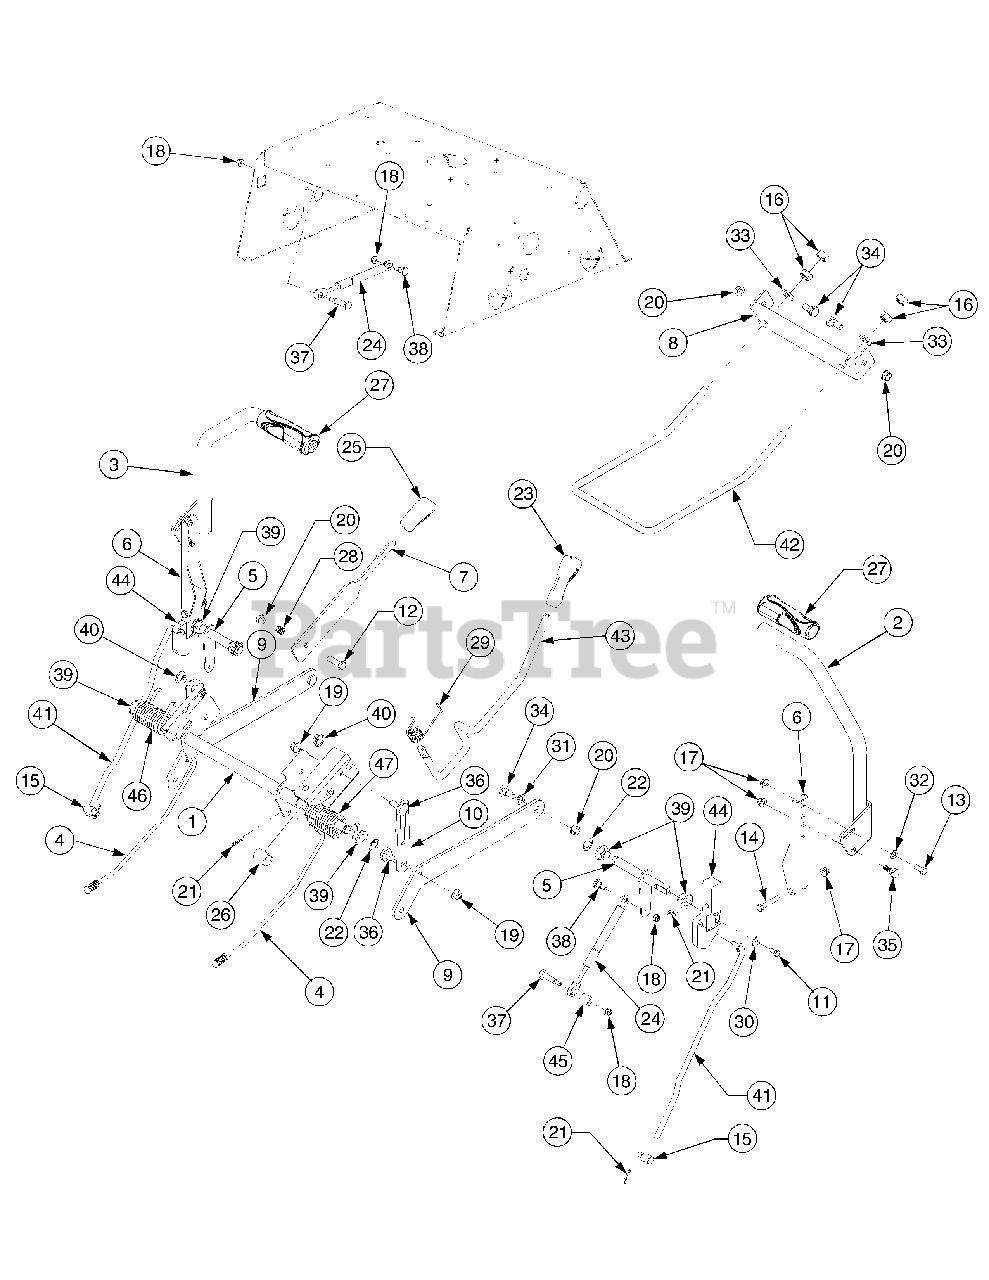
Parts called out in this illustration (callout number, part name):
4	Rod, Brake
5	Shaft, Control
6	Bracket, Lapbar Pivot
11	Screw, Hex Lock, 1/4-20 x .62 GR5
12	Screw, Hex Cap, 3/8-16 x 1.25 GR5
13	Screw, Hex Cap, 5/16-18 x .75 GR5
14	Screw, Hex Cap, 5/16-18 x 1.75 GR5
15	Ferrule, 3/8-24 x .375
16	Nut, Hex, 1/2-13 GR5
17	Nut, Hx Flange Insert Lck, 5/16-18 GrF
18	Nut, Hx Flange Insert Lck, 1/4-20 GrF
19	Nut, Hx Flange Insert Lck, 3/8-16GrF
20	Nut, Hex Flange Lock, 3/8-16 GRF
21	Pin, Internal Cotter
22	E-Ring , .625 Dia. Shaft
23	Grip, Handle
24	Cylinder, Damper
25	Grip, Handle
26	Spacer, .62 x 1.0
27	Grip, Hand
28	Spring, Compression
29	Spring, Torsion RZT
30	Washer, Bell, .265 x .75 x .062
31	Washer, Flat, .51 x 1.0 x .06
32	Washer, Flat, .344 x .688 x .065
33	Washer, Flat, .531 x 1.062 x .134 HT
34	Screw, Shoulder, .498 x .340:3/8-16
35	Screw, Shoulder, .437 x .268:5/16-18
36	Screw, Shoulder, .5 x .434:3/8-16
37	Screw, Shoulder, .374 x 1.16:1/4-20
38	Screw, Shoulder, .375 x .38:1/4-20
39	Bearing, Hex Flange
40	Bearing, Flange, .626 x .938 x .344
41	Rod, Lapbar Control
42	Rod, Deck Front Hanger
43	Rod, Deck Lift Handle
44	Hub, Control
45	Spacer, .385 x .63 x .75
46	Spring, Torsion LH
47	Spring, Torsion RH
